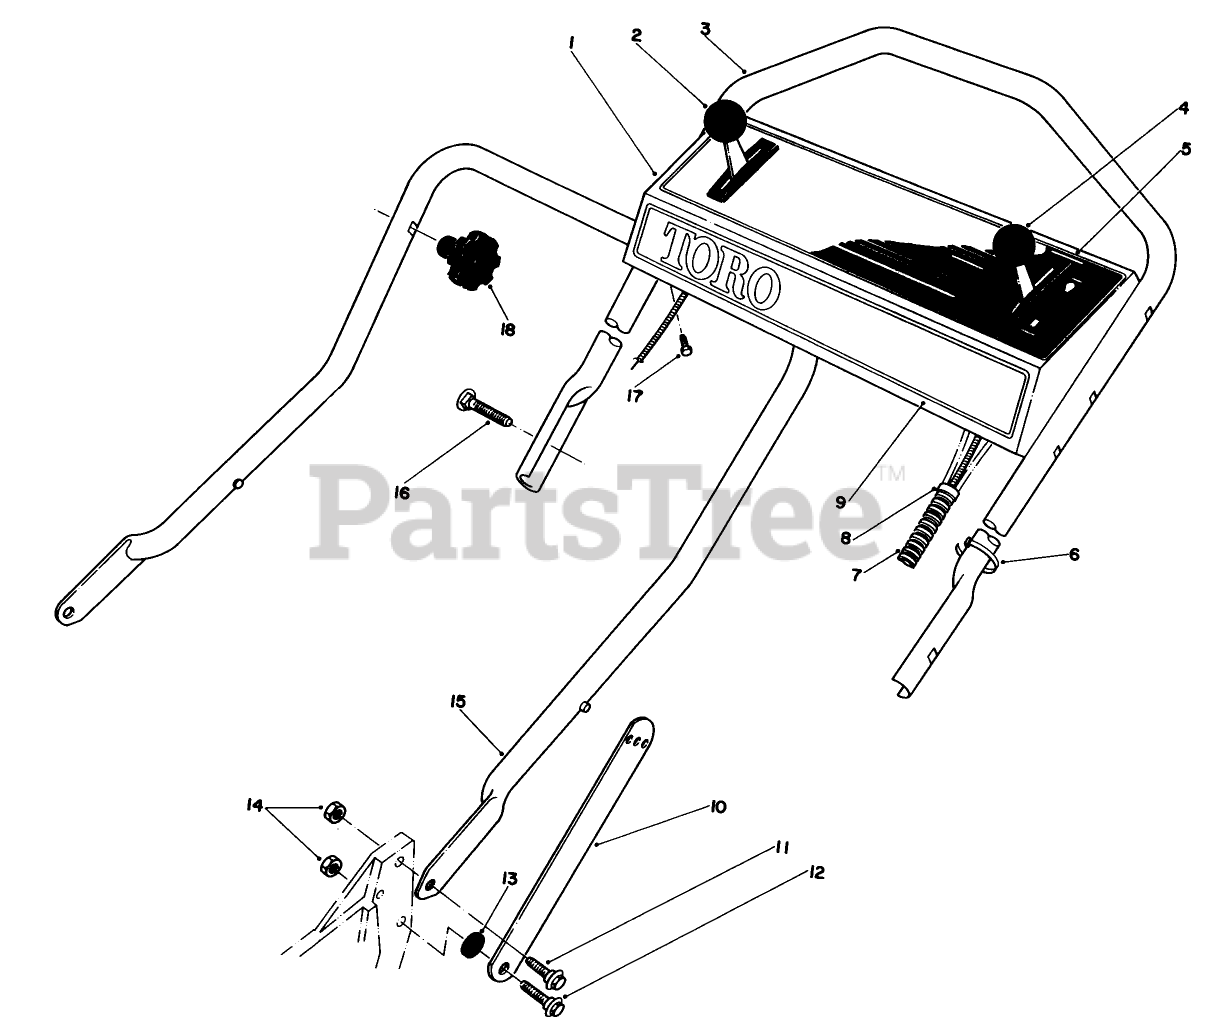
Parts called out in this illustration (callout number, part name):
2	GROUND SPEED CONTROL
6	TIE-CABLE
8	FITTING-RING
11	SCREW-SHOULDER
12	SCREW-SHOULDER
13	SPACER
14	NUT-LOCK, NI
17	SCREW-HWHTF
